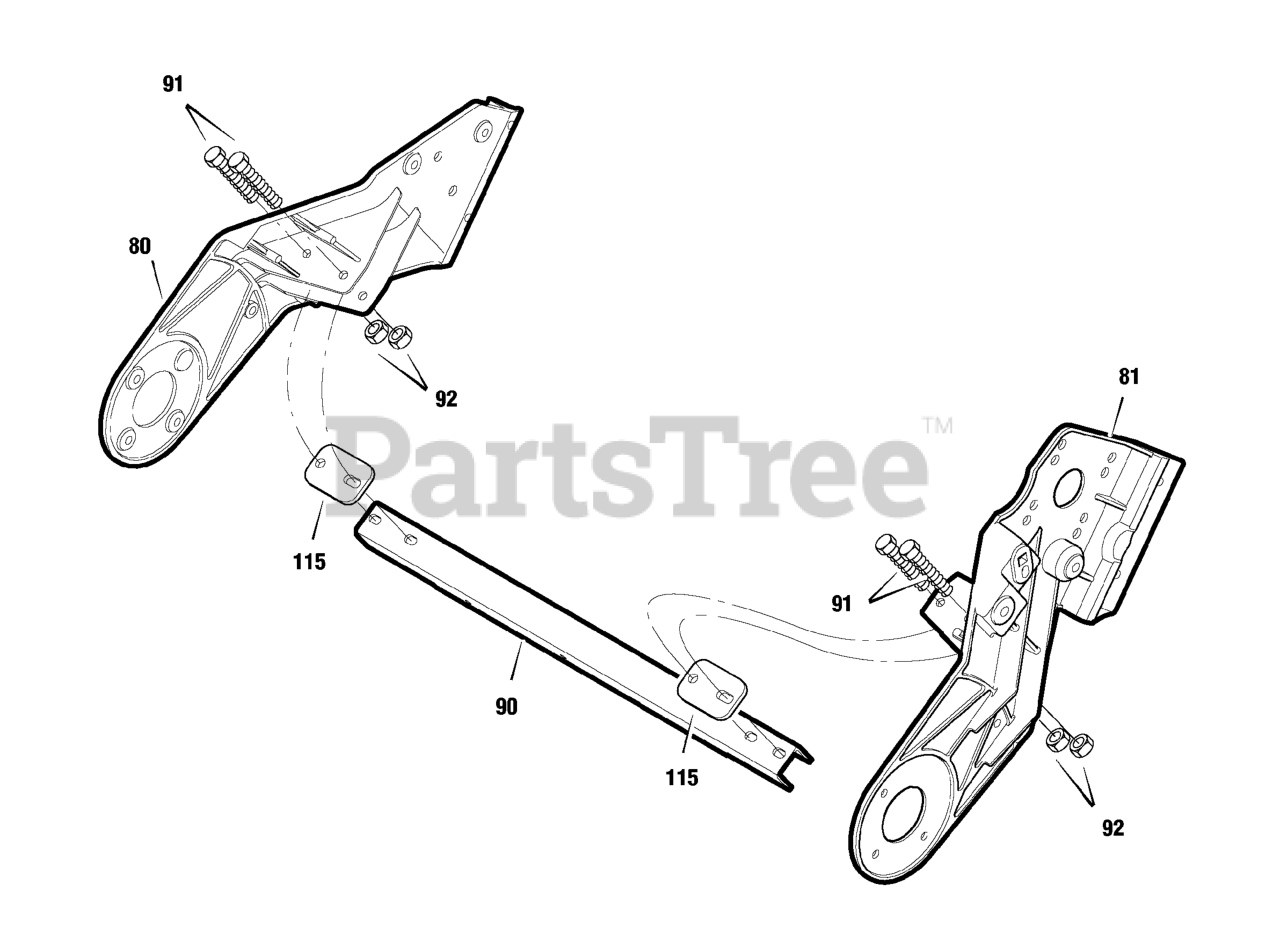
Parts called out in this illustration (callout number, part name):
80	FRAME, SIDE RIGHT HAND
81	FRAME, SIDE LEFT HAND
90	CHANNEL SUPPORT
91	SCREW, 1/4-20 x 2.00
92	NUT, 1/4-20
115	PLATE, BOLTING SUPPORT
